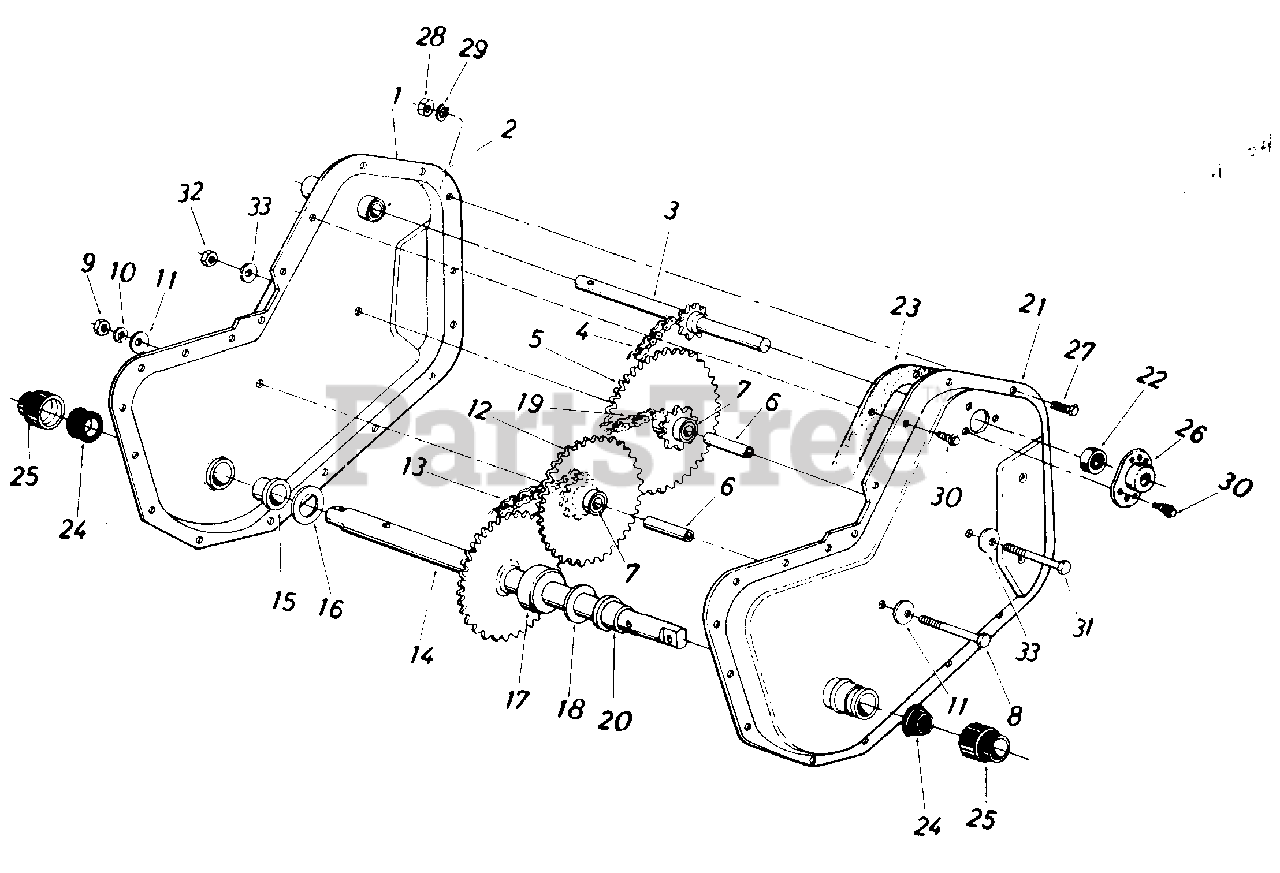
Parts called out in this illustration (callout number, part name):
1	Chain Case Half Ass'y. R.H.
2	Bearing 5/8" I.D. x .813" O.D. x 1.31" Lg.
3	Input Shaft Ass'y.
4	Chain #35-3/8" Pitch x 44 Links
5	Sprocket and Hub Ass'y.
6	Bearing Inner Axle
7	Sleeve Brg. 5/8" I.D. x 3/4" O.D. x 1.50
8	Hex Bolt 3/8-24 x 2.50" Lg.
9	Hex Ins. L-Nut 3/8-24 Thd.
10	L-Wash. 3/8" I.D.
11	Bell-Wash. .41" I.D. x 1.13" O.D. x .03
12	Sprocket & Hub Ass'y. 9T-22T
13	#420 Chain 1/2 Pitch x 28 Links Endless
14	Wheel Shaft Ass'y.
15	Flange Bearing
16	Fl-Wash. .88" I.D. x 1.5" O.D. x .03
17	Spacer 7/8" I.D. x 13/4" O.D. x.68" Lg.
18	Fl-Wash. .88" I.D. x 1.50" O.D. x .03
19	#420 Chain 1/2" Pitch x 30 Links Endless
20	Flange Bearing
23	Gasket
25	Dust Cup
26	Bearing Housing
27	Hex Bolt 1/4-28 x 5/8" Lg.
28	Hex Nut 1/4-28 Thd.
29	L-Wash. 1/4" I.D.
30	Hex Wash. S-Tap Scr. 1/4-20 x .50" Lg.
31	Hex Bolt 5/16-18 x 2.5" Lg.
32	Hex Cent. L-Nut 5/16-18 Thd.
33	Fl-Wash. 5/16" I.D.
